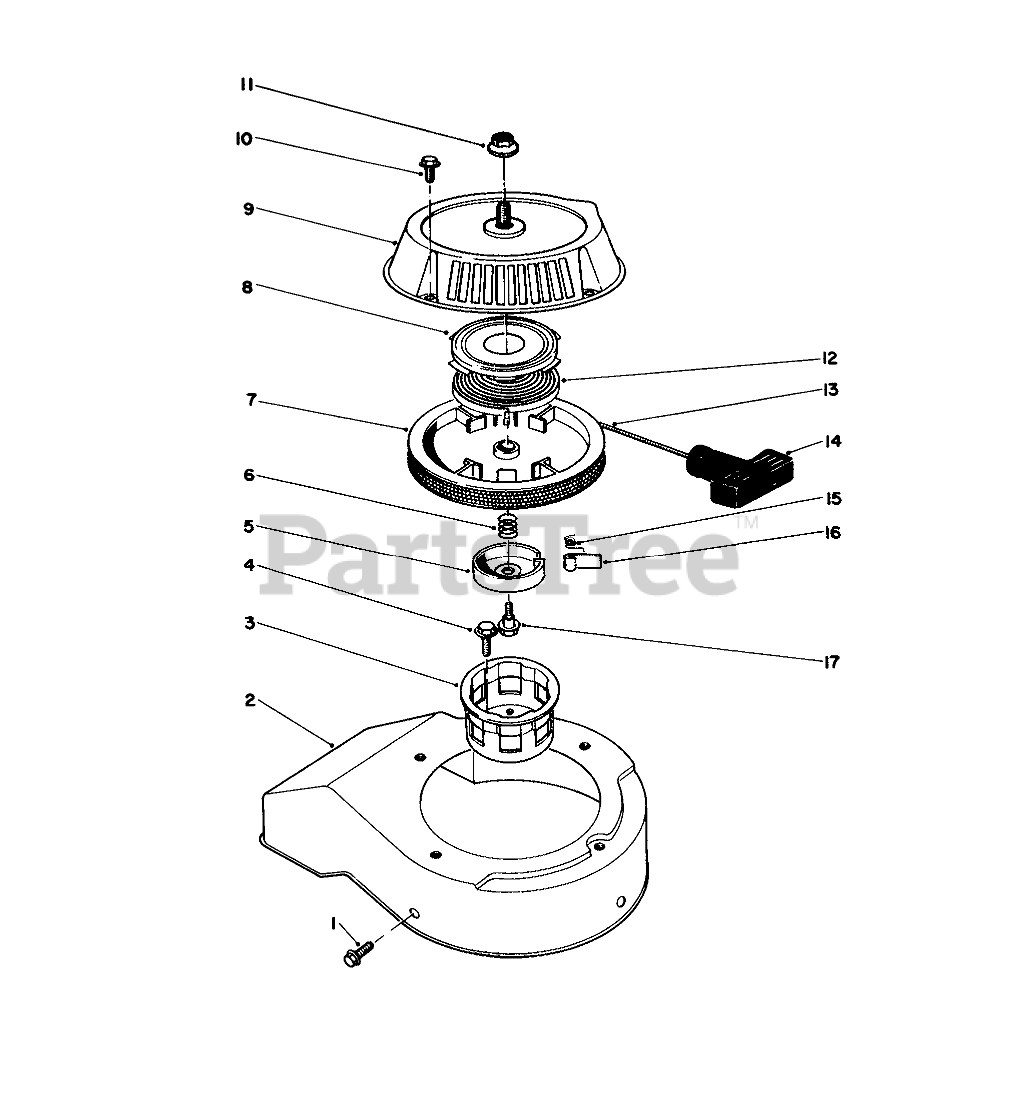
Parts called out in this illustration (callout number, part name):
2	BLOWER SHROUD
3	CUP - STARTER
5	RETAINER
6	SPRING
8	Retainer-Recoil Spring
9	RECOIL CASE
10	MOUNTING SCREW
11	NUT (F/W & PPP)
12	Spring-Recoil (Incl. Ref. #8)
13	ROPE-STARTER
14	HANDLE-RECOIL
15	SPRING
